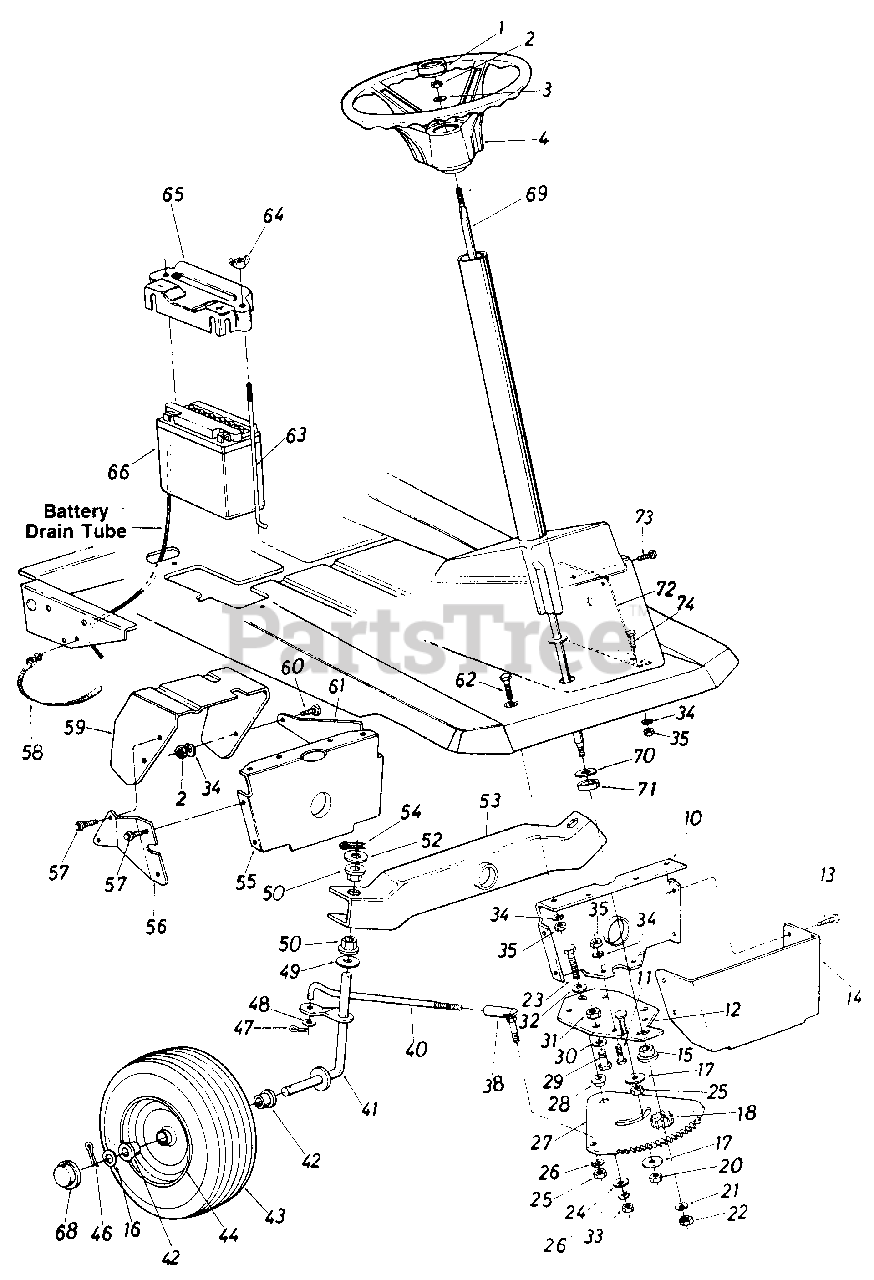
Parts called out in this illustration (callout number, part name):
1	Steering Wheel Cap
2	Hex L-Nut 5/16-24 Thd.
3	Bell-Wash. .345" I.D. x .88" O.D.
4	SteeringWheel Ass'y.
10	Pivot Bar Bracket
11	Hex Bolt 5/16-18 x .75" Lg.
12	Steering Gear Support Brkt.
13	Hex Wash. Hd. AB-Tap Scr. 1/4 X .62" Lg.
17	Fl-Washer 3/8" I.D. x 1.37" 0. D.
18	Steering Pinion Gear
20	Hex L-Nut 3/8-24
21	Fl-Wash. .34" I.D. x .68" O.D.
22	Hex Nut 5/16-24 Thd.
23	Hex Bolt 3/8-24 x 1.25" Lg. (Grade 5)
24	Fl-Wash. .385" I.D. x 1.38"
25	Hex Nut 3/8-24 Thd.
26	L-Wash. 3/8" I.D.
27	Steering Gear Segment
28	Shoulder Spacer .622" Dia. x .218
29	Hex Bolt (Nylon) 1/2-13 x .75"
30	Fl-Wash. .530" I.D. x .930"
31	Hex Nut 1/2-13 Thd.
32	Bell-Wash. .385" I.D. x .88"
33	Hex Nut 3/8-24 Thd.
34	L-Wash. 5/16" I.D.
35	Hex Nut 5/16-18 Thd.
38	Ball Joint Ass'y. 3/8-24 Thd.
40	Steering Tie Rod
41	Front Axle Ass'y.-R.H.
42	Flange Bearing .632" I.D.
43	Front Wheel Ass'y. Comp.
43	Wheel Ass'y. Com
44	Front Wheel Rim Only
46	Cotter Pin 1/8" Dia. x 1.25"
47	Cotter Pin 1/8 Dia. x 1.00
48	Fl-Wash. .385" I.D. x .87"
49	Fl-Wash. .635" I.D. x 1.24"
50	Hex Flange Bearing
52	Fl-Wash. .635" I.D. x 1.12n
53	Pivot Bar Ass'y.
54	Cotter Pin 1/8" Dia. x 1"*
55	Pivot Bar Bracket
56	Bracket Reinforcement- R.H.
57	Hex Wash. Hd. AB-Tap Scr. 1/4 x .62" Lg.
58	Cable Tiet
59	Clutch-Brake Pedal Ass'y.
60	Hex Bolt 5/16-18 x .75" Lg.
61	Bracket Reinforcement-L.H.
62	Hex Bolt 5/16-18 x .75" Lg.
63	Battery Hold Down Rod
64	Wing Nut Solid 1/4-20 Thd.
65	Battery Hold Down Cover
66	12V Battery
68	Hub Cap
69	Steering Shaft Ass'y.
70	Fl-Wash. .635" I.D. x 1.24" O.D.
71	Spacer (Plastic)
74	Hex Bolt 5/16-18 x 2.00" Lg.
